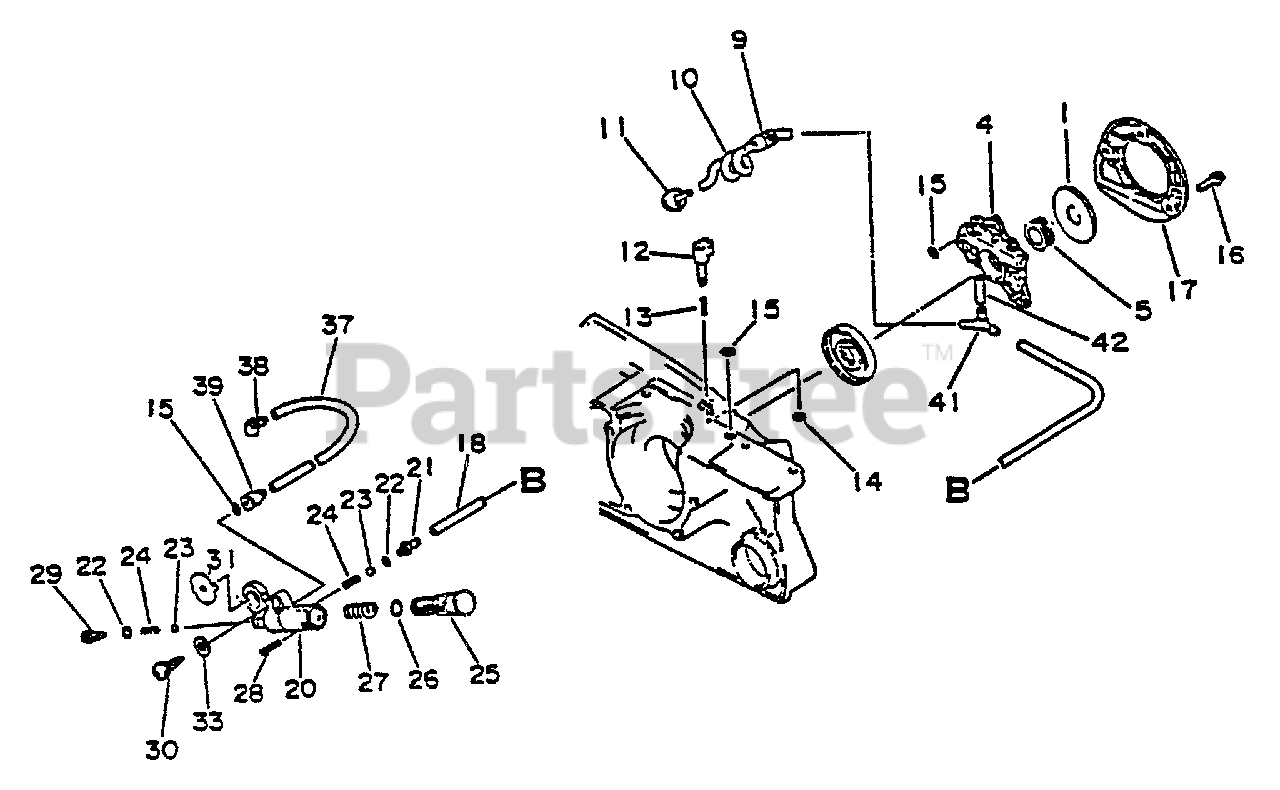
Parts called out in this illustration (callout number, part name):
1	GEAR, WORM
4	AUTO-OILER KIT
5	GEAR, WORM
10	PIPE, OIL
11	FILTER, OIL
14	E-RING 3
15	O-RING 3
16	BOLT 4×14
17	COVER, OIL PUMP - GRAY
18	PIPE, OIL
20	BODY, OIL PUMP
21	CONNECTOR, PIPE
23	VALVE, BALL
24	SPRING, VALVE
25	PISTON, OIL PUMP - ORANGE
26	O-RING 7 MM
28	PIN, SPRING 2×16
29	ADAPTOR, OIL PUMP
30	SCREW - 5×20
31	BRACKET, OIL PUMP
33	WASHER 5.5×12×0.8
37	PIPE 3×6×125 BLACK
38	CONNECTOR, PIPE
39	CONNECTOR, PIPE
41	PIPE, OIL 3×6×20
42	CONNECTOR, PIPE
